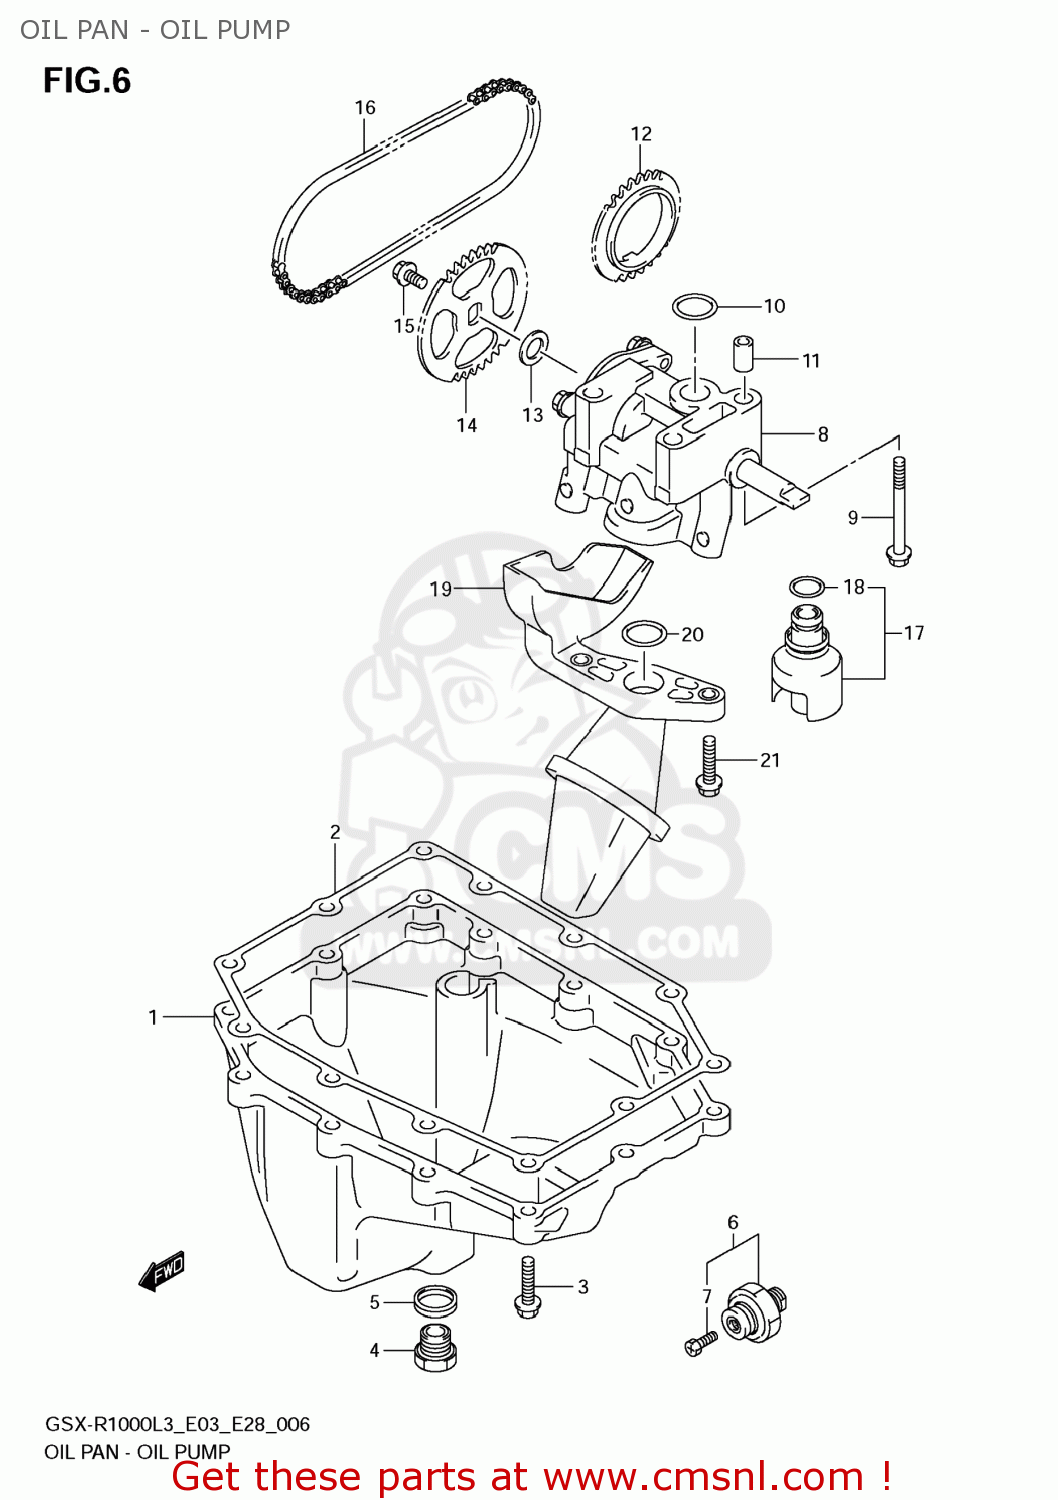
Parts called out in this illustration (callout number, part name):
1	PAN,OIL
2	GASKET,OIL PAN(ASB) (NAS)
3	BOLT
4	PLUG(14X20)
5	GASKET(13.8X18.8X4.8) (NAS)
6	SWITCH ASSY,OIL PRESSURE
7	BOLT,OIL PRESSURE SWITCH
8	PUMP ASSY,ENGINE OIL
9	BOLT
10	O RING(D:2.4,ID:15.8)
11	PIN
12	SPROCKET,OIL PUMP DRIVE
13	SHIM(10X18X0.5)
14	SPROCKET,OIL PUMP DRIVEN
15	BOLT(6X12)
16	CHAIN,OIL PUMP DRIVE
17	VALVE ASSY,OIL RELIEF
18	O RING(D:1.9,ID:13)
19	STRAINER ASSY,ENGINE OIL
20	O RING(D:2.62,ID:20.3)
21	BOLT
